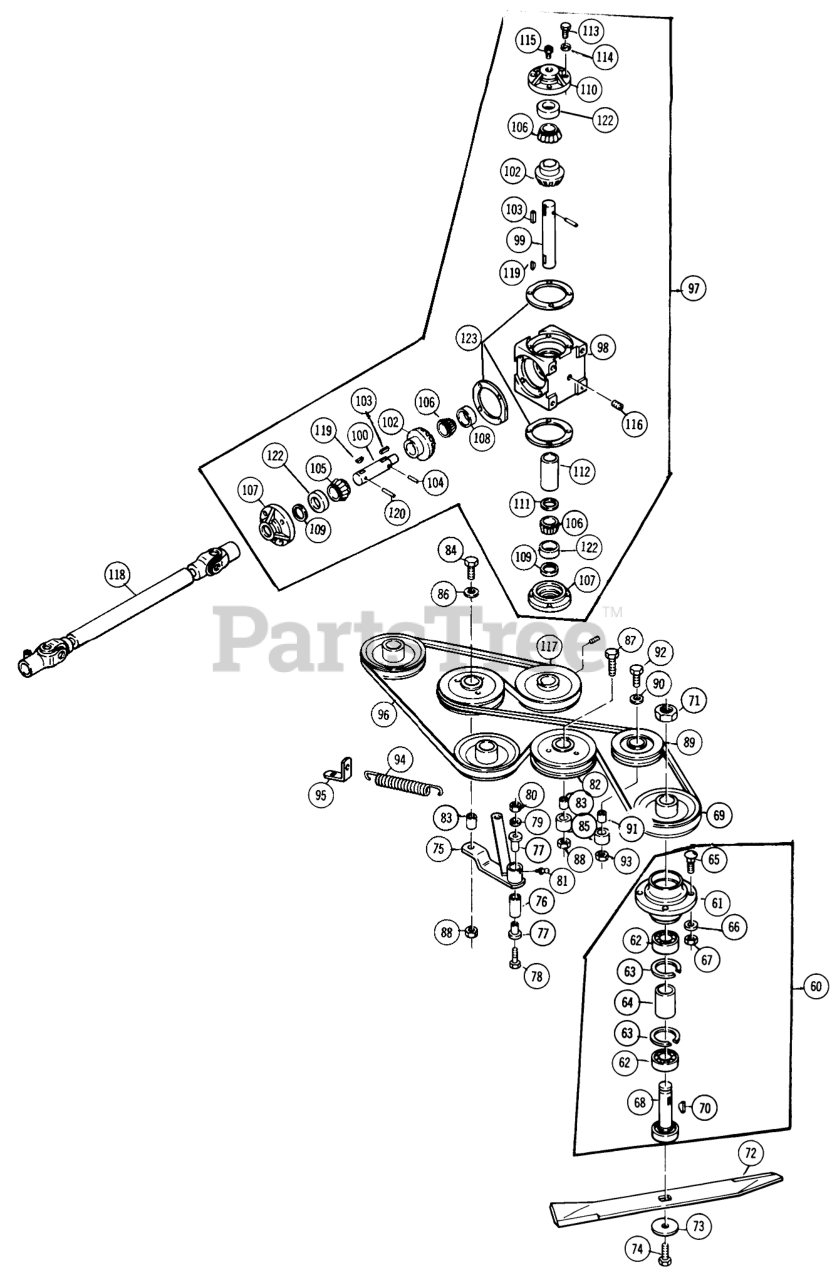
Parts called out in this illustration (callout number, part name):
60	Spindle Housing Assembly
61	Spindle Housing
62	Bearing
63	Snap Ring (Internal)
64	SPACER-SPINDLE
65	Bolt
66	Washer
67	Nut
68	Spindle Shaft Assembly
69	PULLEY-END
70	WOODRUFF KEY 1/4X7/8
71	Jam Nut 1-14
72	BLADE
73	Drive Washer
74	Bolt
75	Idler Arm
76	Bushing
77	BUSHING
78	Bolt
79	Washer
80	Nut
81	Zerk
82	Flat Idler Pulley
83	SPACER
84	BOLT
85	SPACER
86	Washer
87	Bolt
88	Nut
89	PULLEY-V IDLER
90	Washer
91	Spacer
92	Bolt
93	Nut
94	SPRING-EXTENSION
95	Spring Anchor
96	V-BELT, DECK DR.
97	Gear Box Assembly
98	Housing
99	Shaft
100	Shaft
101	Toggle
102	Bevel Gear
104	Roll Pin
105	Tapered Roller Bearing
106	Tapered Roller Bearing
107	CAP ASSY-SERVICE ONL
108	Bearing Cup
109	Seal
110	Side Plate Gasket
111	Washer
112	Spacer
113	HHCS
114	Lockwasher
115	Relief Valve
116	Washer
117	Washer
118	SHAFT-PTO DRIVE
119	WOODRUFF KEY 1/4X7/8
120	Spirol Pin 1/4 x 1 3/4
121	Set Screw
122	CUP-BEARING--SERVICE
123	Gasket, .002 Thick
